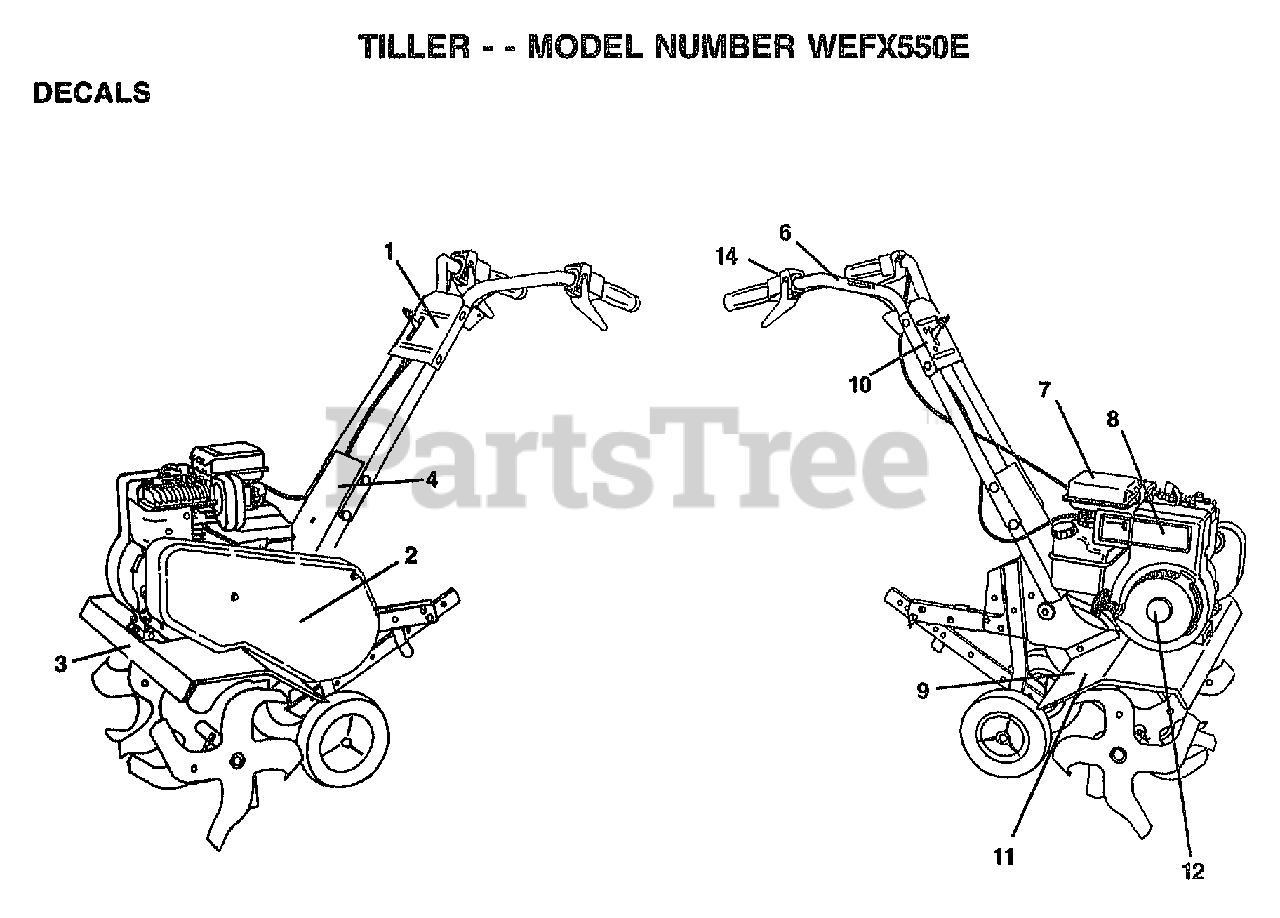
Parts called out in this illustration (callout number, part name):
1	DECAL.LOGO.CONTROL
3	DECAL.DESCRIPTION
4	DECAL.HP.REVERSE
6	DECAL-PLACEMENT
7	DECAL TI
9	DECAL-WARNING
10	"DECAL CONTROL,PNL"
11	DECAL.EURO.ST.CE.
12	DECAL
13	DECAL.CONTROL FOR
14	DECAL.CONTROL.REV
